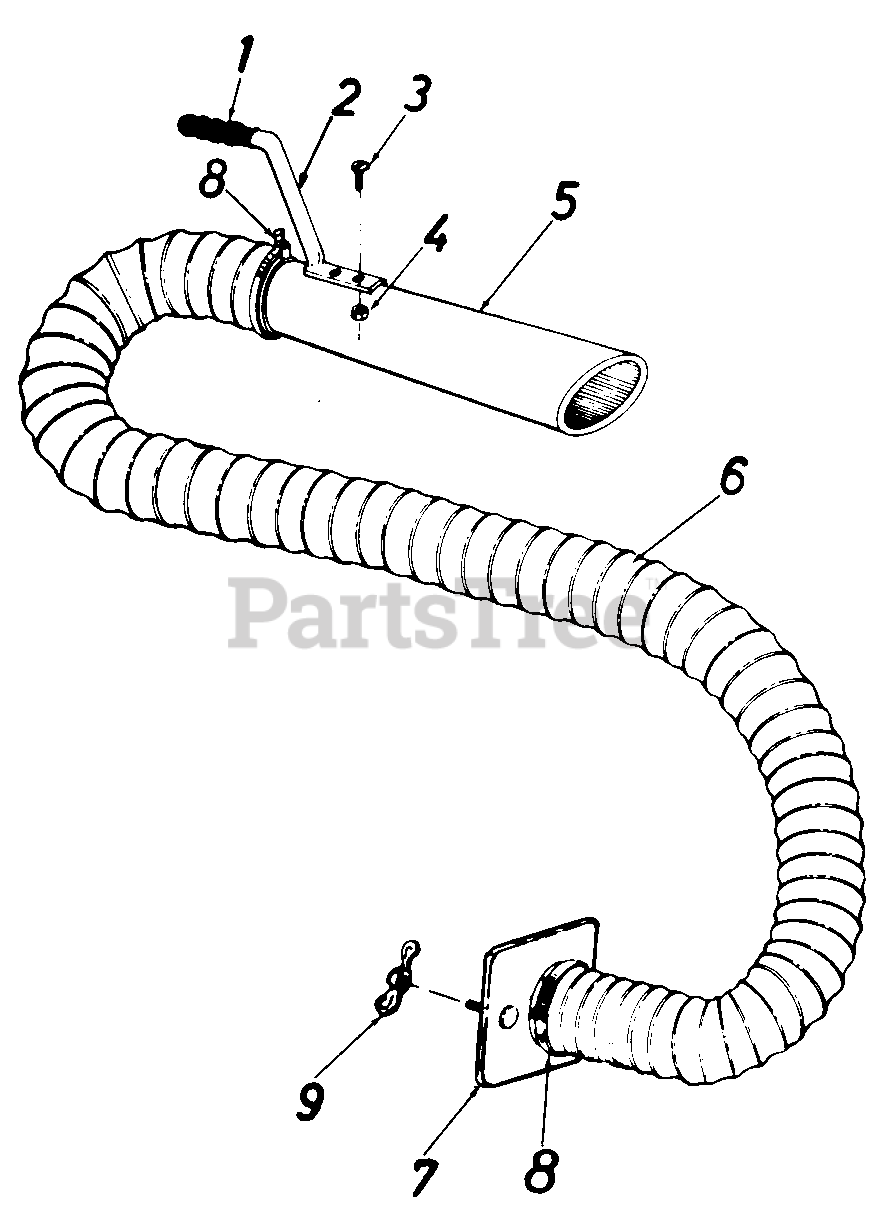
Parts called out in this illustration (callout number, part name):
1	Handle Grip
2	Handle
3	Truss Sems Scr. 10-24 x 1/2" Lg.
4	Hex Nut 10-24Thd.
5	Hose Nozzle
6	Flexible Hose 4" Dia. x 10' Lg.
7	Hose Adapter Plate
8	Hose Clamp-For 4" Dia. Hose
9	Wing Nut 1/4-20Thd.
